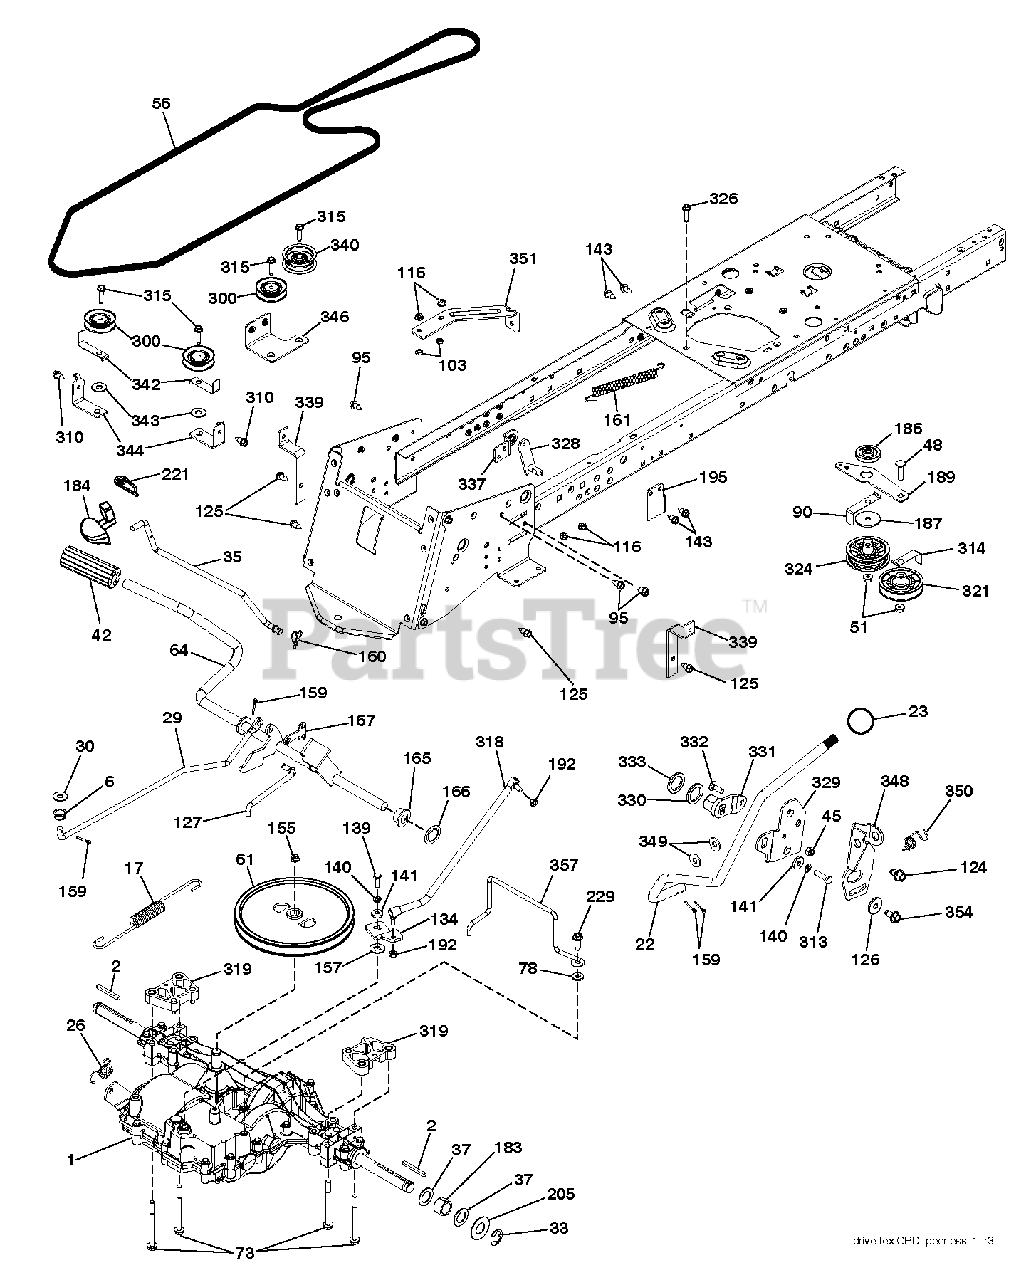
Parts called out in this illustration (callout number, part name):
2	SQUARE KEY
6	MANDREL ASS'Y
17	SPRING SPRING BRAKE GEAR CRD
22	ROD ROD SHIFT CRD TEX
23	KNOB.DUCKHEAD.1/2
26	SPRING,BRAKE RETURN
29	ROD.BRAKE.GEAR.CRD.TEX
30	WASHER
35	ROD.CNTRL.PARK.PREDATOR.LT.TEX
42	PEDAL COVER T
45	LOCKNUT.NYLOC.1/4-20
48	BOLT.3/8-16X1.50
51	NUT LOCK FLG 3/8-16 UNC
56	BELT BELT V CRD GEAR
61	PULLEY
64	SHAFT.ASM.PEDAL.BRAKE.
73	BOLT.HEX.FLNG.5/16-18X3.75
90	BRACKET KEEPER BELT CLUTCHING
95	SCREW, 3/8-16X3/4
103	JAM NUT TI
116	NUT LOCK HEX FLANGE 5/16-18
124	BOLT.SHOULDER.5/16-18X
125	SCREW
126	WASHER.SRRTD.5/16
127	RP LINK.CLUTCH.GROUND.DRIVE
139	BOLT 1/4-28X3/4
140	LOCKWASHER
143	SCREW LT
155	RETAINING RING LT
157	WASH-SHFT PLT LT
159	COTTER PIN
160	RETAINER CLIP
161	SPRING, RETURN LT
165	BUSHING.SHAFT.BRAKE.HAND
166	NUT.PUSH.625
167	LATCH.BRAKE.SPRING
183	SPACER AXLE
184	HANDLE.PARKING.BRK.PRED.LT.RED
186	SPACER.RETAINER
187	WASHER 12/32X2X10GA
189	BELLCRANK BELLCRANK GROUNDDRI
192	NUT LOCK CENTER 1/4 -28 FNTHD
221	RETAINER.SPRING.CLIP.H
229	SCREW 5/16-18X1
300	PULLEY.V-IDLER.
314	RETAIN BELT
315	BOLT.5/16-18X1.25
318	GEAR LINK SHIFT GEAR
319	SPACER SPACER TRANSAXLE TEX C
321	IDLER PULLEY
326	BOLT CARRIAGE
328	SHAFT SHAFT SHIFT FRONT
329	BRACKET.SHIFT.MOUNT
330	WASHER.NYL.7/8IDX.105"HYD CR
331	RB HUB.SHIFT
332	BOLT
333	WASHER.WAVE.SPRING
337	BRACKET BRACKET SUPT SHIFT CR
339	STRAP STRAP TORQUE K46 CRD TE
340	IDLER.FLAT.2.25.INCH
342	BELT GUIDE
344	BRACKET BRACKET IDLER CRD TEX
348	BRACKET.PIVOT.LEVER
349	WASHER
350	SHIFT SPRING
351	BRACKET BRACKET DECK SWAY
354	CAPSCREW.HXHD.FLG.5/16-18X.625
357	KEEPER KEEPER
